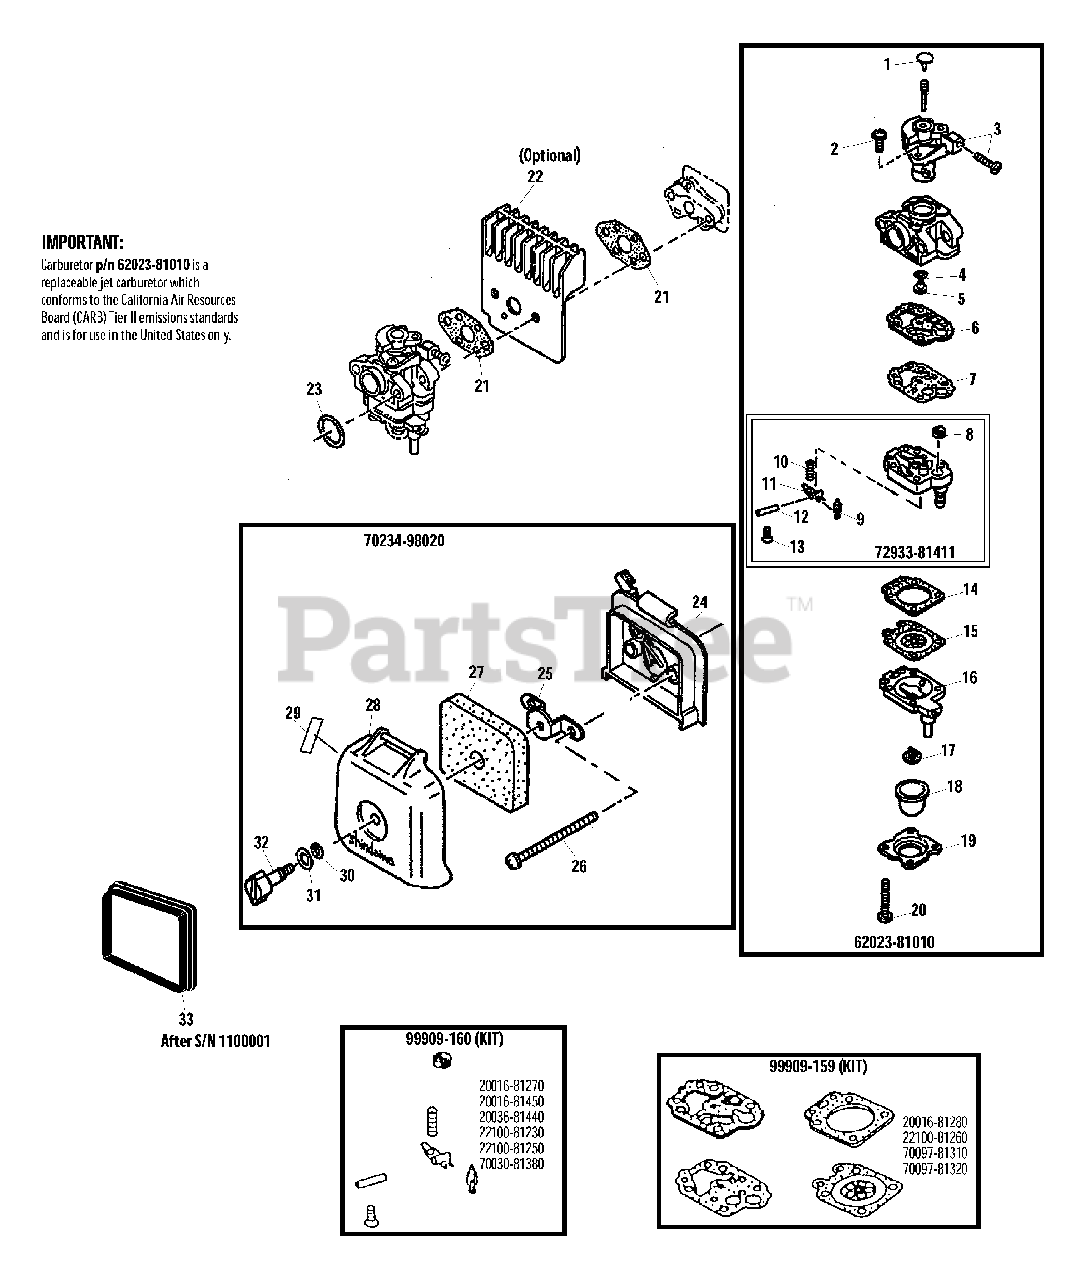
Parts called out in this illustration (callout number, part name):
1	PLUG, WELCH
2	SCREW
3	THROTTLE VALVE ASSY
4	O-RING
5	JET, MAIN
6	GASKET, PUMP
7	DIAPHRAGM, PUMP
8	STRAINER
9	VALVE, INLET NEEDLE
10	SPRING, METERING LEVER
11	LEVER, METERING
12	PIN, METERING LEVER
13	SCREW, METERING LEVER PIN
14	GASKET, METERING
15	DIAPHRAGM, METERING
16	BASE, PURGE
17	VALVE, CHECK
18	BULB, PURGE
19	RETAINER, PURGE BULB
20	SCREW, PUMP COVER
21	GASKET
22	DEFLECTOR, HEAT
23	O-RING - 15
24	CASE, AIR FILTER
25	PLATE, PREVENT
26	SCREW - 5X67
27	FILTER, AIR - FOAM
28	COVER, AIR FILTER
29	LABEL - CHOKE
30	O-RING
31	WASHER - CONICAL
32	THUMBSCREW
33	FILTER, AIR - HEAVY DUTY
62023-81010	CARBURETOR
70234-98020	AIR FILTER ASSY
72933-81411	BASE, PURGE
99909-159	DIAPHRAGM/GASKET KIT
99909-160	REPAIR KIT
